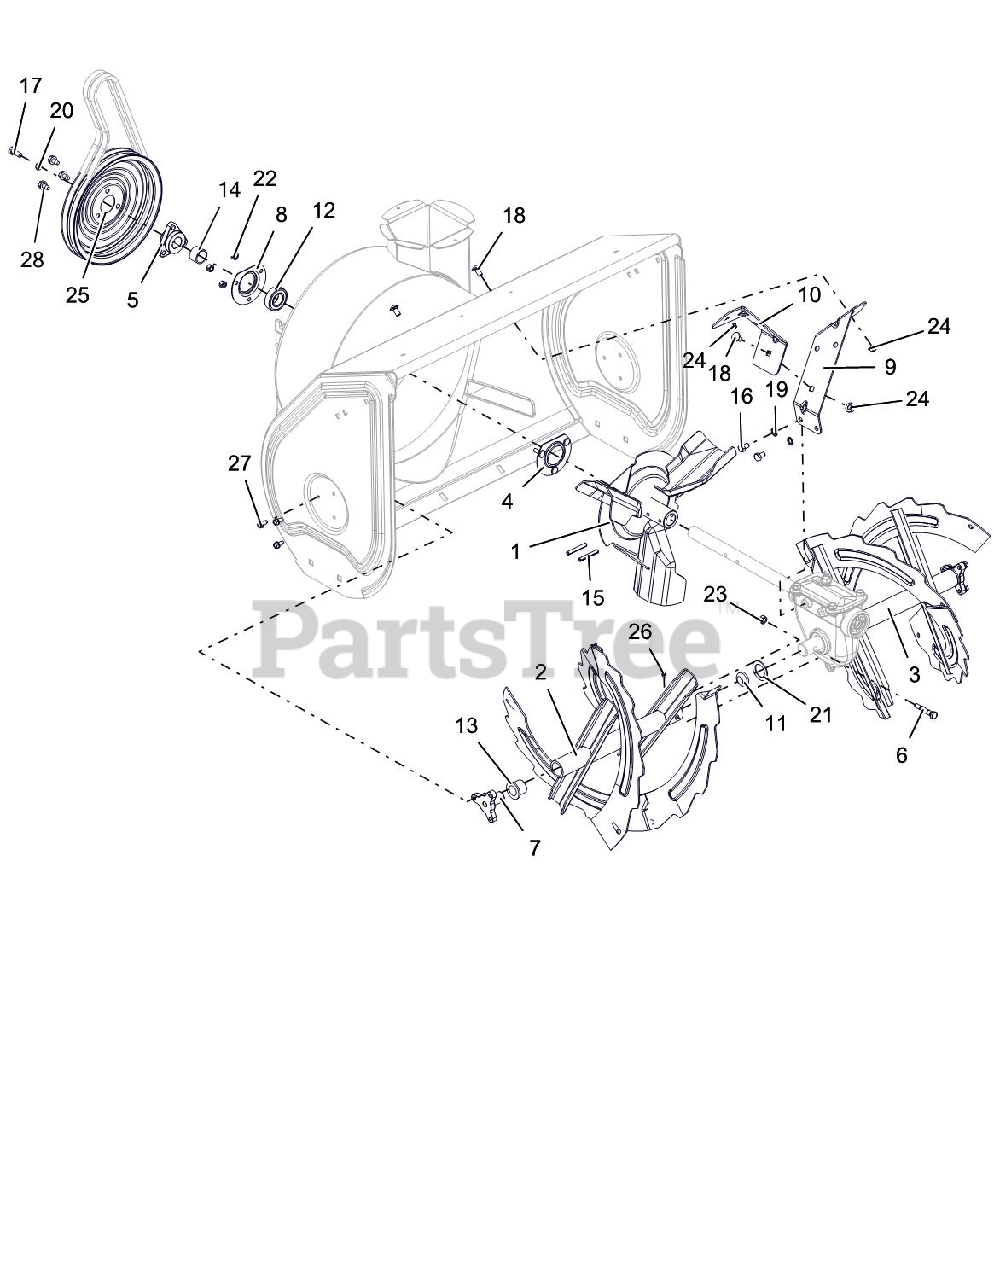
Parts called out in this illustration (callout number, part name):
1	IMPELLER, 3 BLADE-14"
2	RAKE, RH W/ZERK - 28"
3	RAKE, LH W/ZERK - 28"
4	BEARING FLANGE
5	PULLEY HUB, D-BORE .87 DELUXE
6	SHEAR BOLT SERVICE ASSEMBLY
7	SUPPORT, RAKE BUSHING
8	BEARING FLANGE
9	BRACKET, GEARCASE SUPPORT - LH
10	BRACKET, GEARCASE SUPPORT - RH
11	PLUG, RAKE TUBE
12	BRG-BALL .876 X 1.750 X .50
13	BSHG-FLG, NY.778 ID X 1.018 OD
14	BSHG,SPCR .895X1.065X.693
15	PIN-ROLL .250X1.75
16	@BLT-HEX .31-18X.50 GR5 YWZC
17	BLT-HEX .31-24X.75 YWZC GR5
18	BLT-RDHDSQSHNK.31-18X.62 YZ-LK
19	@WSHR-LK-EXT.326X.599X.031YWZC
20	WSHR-LK .312X.097 HVY YWZC
21	WSHR-FL-STL 1.010X1.505X.062YZ
22	@NUT-LK-CTR .25-20 YWZC
23	@NUT-LK-CTR .31-18 YWZC
24	@NUT-LK-TOP-FLG .31-18 YWZC
25	PULLEY, SPIN FORM DUAL GROOVE
26	ZERK,FITTING .25X.125 DRIVE IN
27	SCR-TAP .25-20X.50 HWH TR YWZ
28	@SCR-TAP .31-18X.50 HWH TR YWZ
